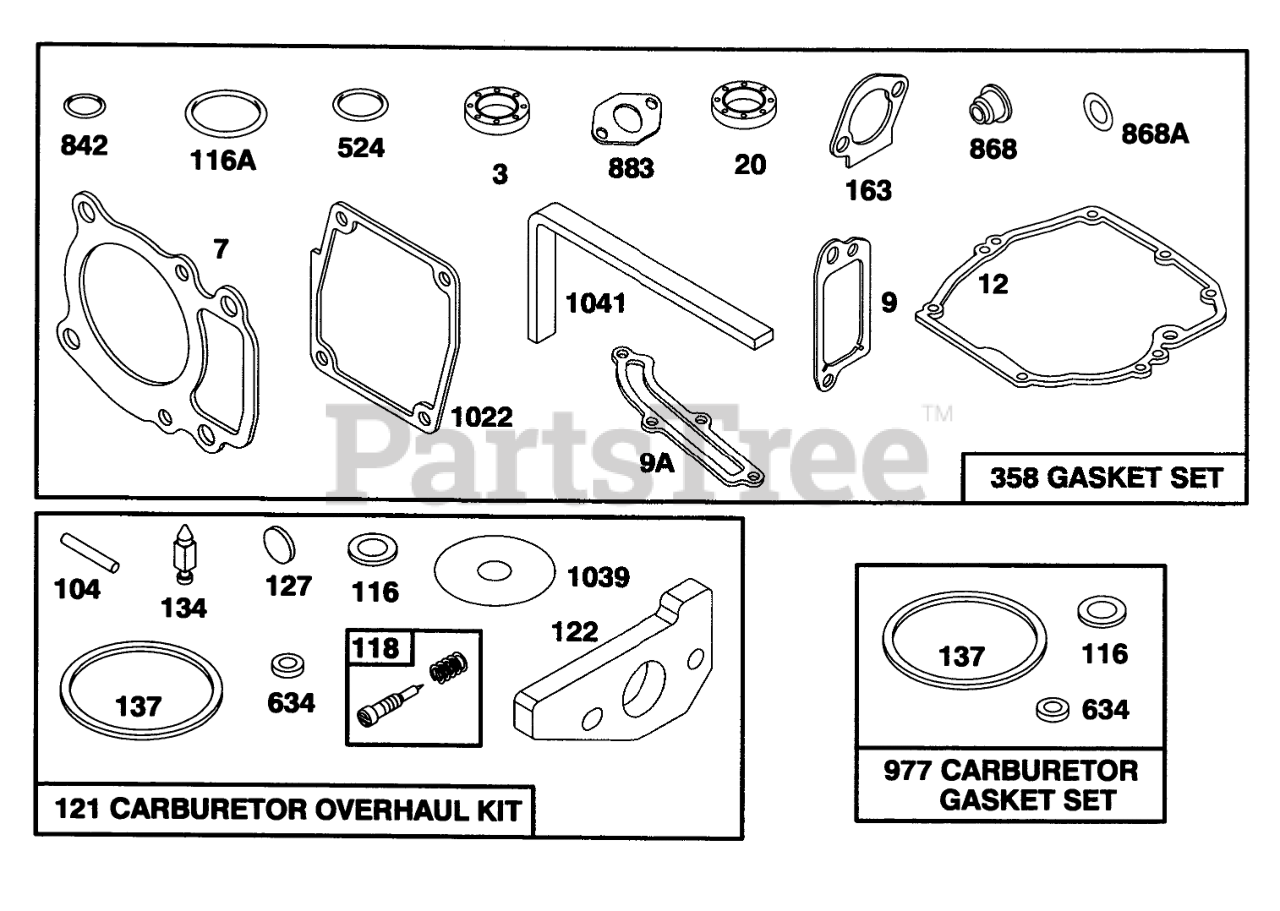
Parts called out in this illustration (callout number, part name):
3	SEAL - OIL
7	CYLINDER HEAD GASKET
9	BREATHER GASKET
9A	GASKET-BREATHER
12	ENGINE BASE GASKET
20	SEAL-OIL
33	EXHAUST VALVE
104	FLOAT HINGE PIN
116	SEALING GASKET
116A	O RING SEAL
118	VALVE KIT - NEEDLE
121	CARBURATOR OVERHAUL KIT
122	ADAPTER ASSEMBLY
127	PLUG
134	Valve-Inlet (Includes Seat)
137	FLOAT BOWL GASKET
163	AIR CLEANER GASKET
358	GASKET SET
524	O-RING
634	SEAL WASHER
842	O-RING
868	SealAssy-Valve
868A	Seal-Valve
883	EXHAUST GASKET
977	CARBURATOR GASKET SET
1022	ROCKER COVER GASKET
1039	FLOAT LIMITER
1041	SEAL - FOAM
